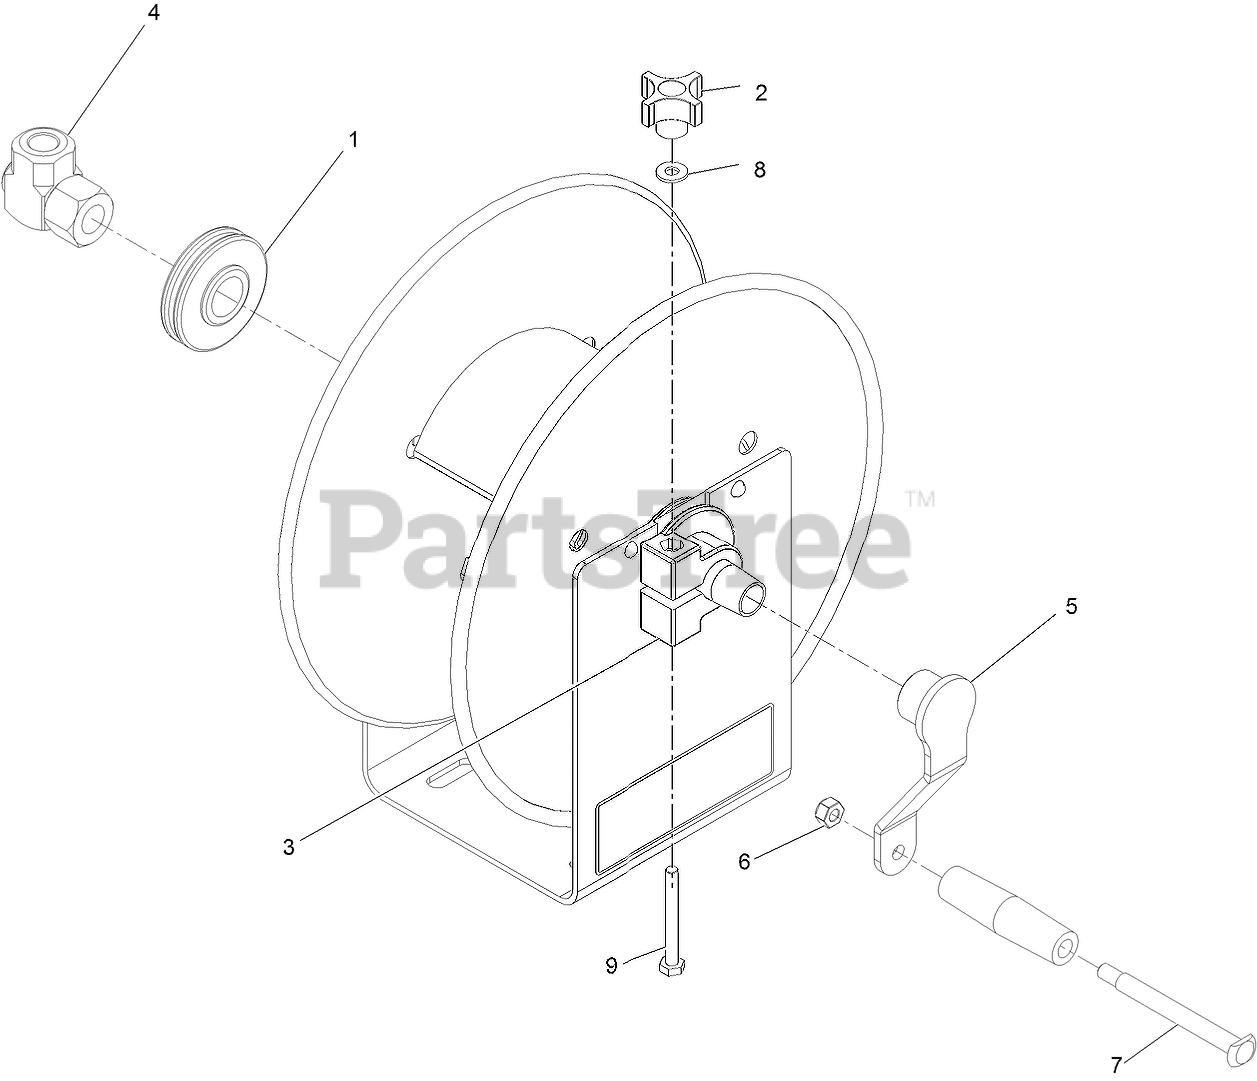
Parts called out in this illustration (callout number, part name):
1	PLASTIC BEARING
2	HOSE REEL BRAKE KNOB
3	BRAKE/BEARING 6329-1-1
4	SWIVEL 3/8" NPT
5	Crank-Reel
6	NUT-HEX
7	BOLT, HOSE REEL HANDLE
8	Washer-Flat
9	SCREW-HH
